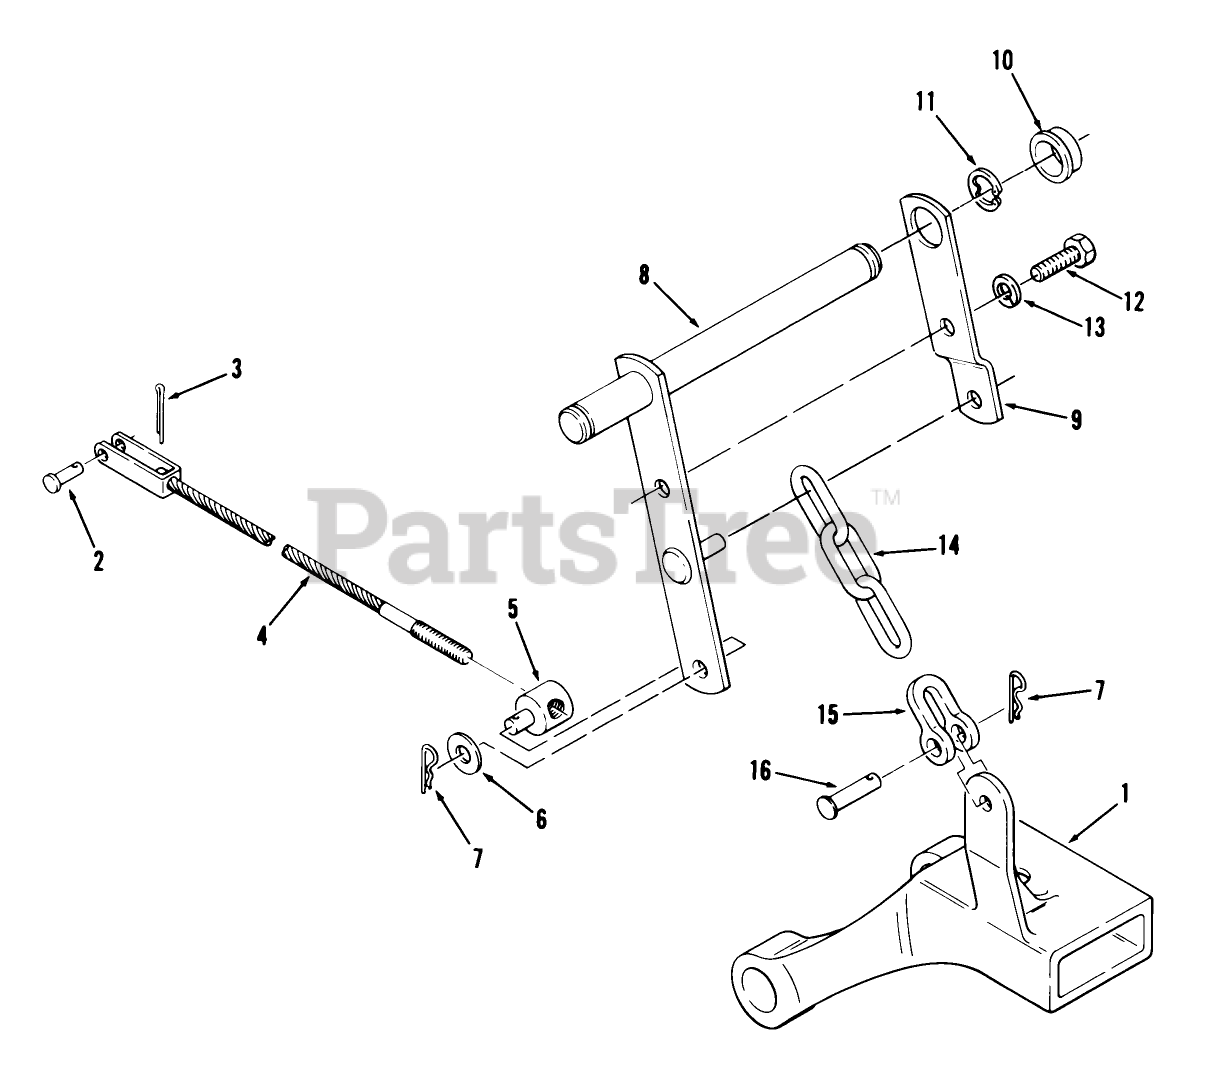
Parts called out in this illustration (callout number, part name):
1	Hitch
2	Pin
3	Cotter Pin
4	ASSY-LIFT CABLE
5	TRUNNION-CLUTCH ROD
6	Washer
7	Hairpin
8	Lever Assy.
9	LOCK BRACKET R
10	BUSHING
11	E-RING
12	Bolt
13	Lockwasher
14	CHAIN-LIFT
15	Clevis
16	Clevis Pin
